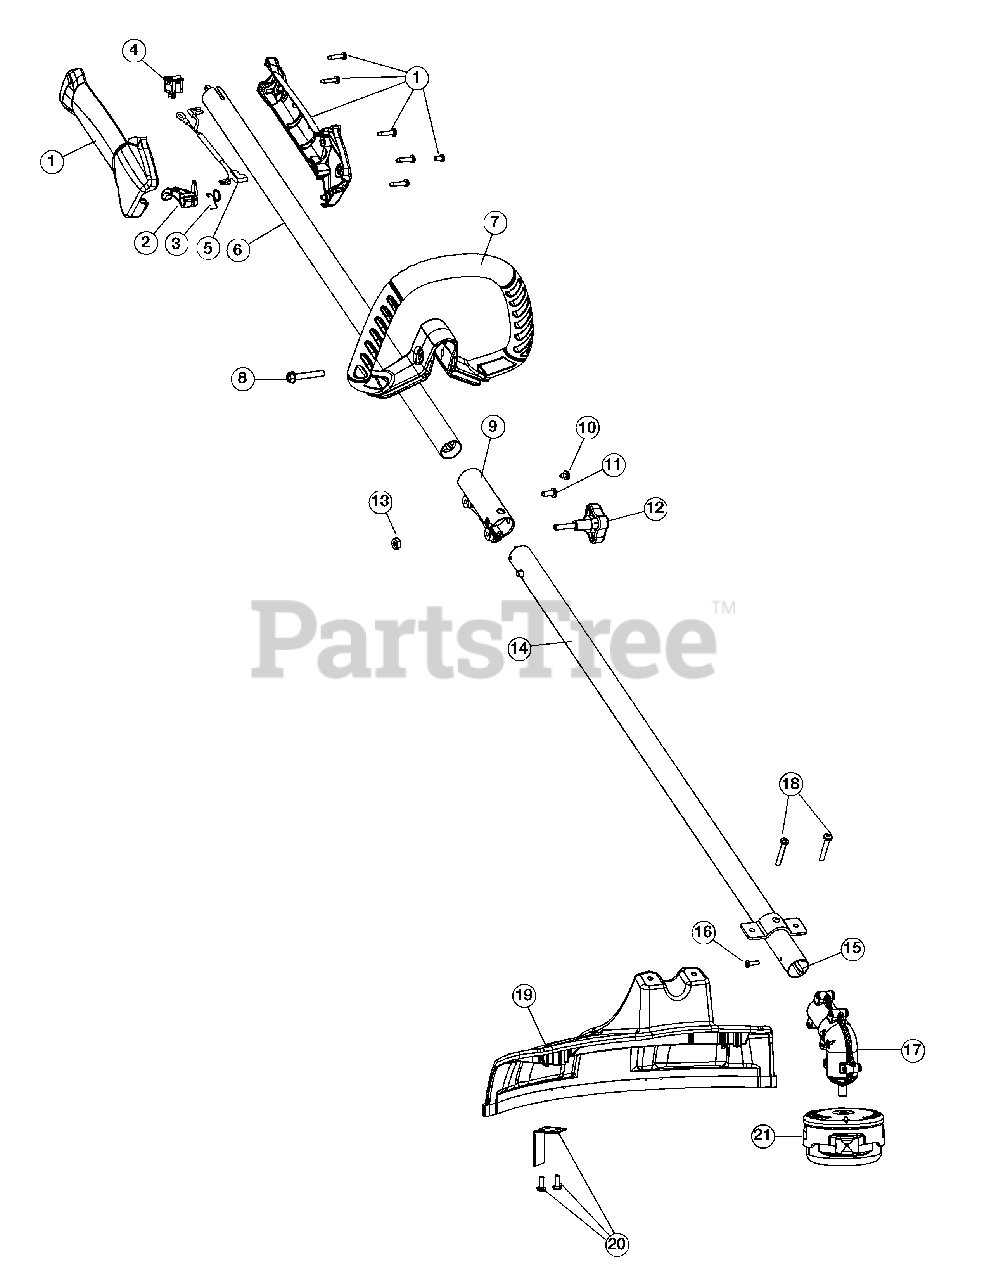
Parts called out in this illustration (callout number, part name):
1	Throttle Housing Assembly (Incl. 2-4)
2	Throttle Trigger
3	Throttle Trigger Spring
5	Throttle Cable Assembly
6	Upper Drive Shaft Housing Assembly
7	Deluxe D-Handle Assembly (Incl. 8)
9	Split Boom Coupler (Incl. 10-13)
12	Adjustment Knob (Incl. 13)
13	Knob Retaining Nut
14	Lower Drive Shaft Housing Assembly
15	Lower Flexible Drive Shaft
16	Anti-Rotation Screw
17	Gear Box Assembly (Incl. 16)
18	Shield Mounting Screws
19	Shield Assembly (Incl. 20)
20	Blade Assembly
21	Cutting Head Assembly
